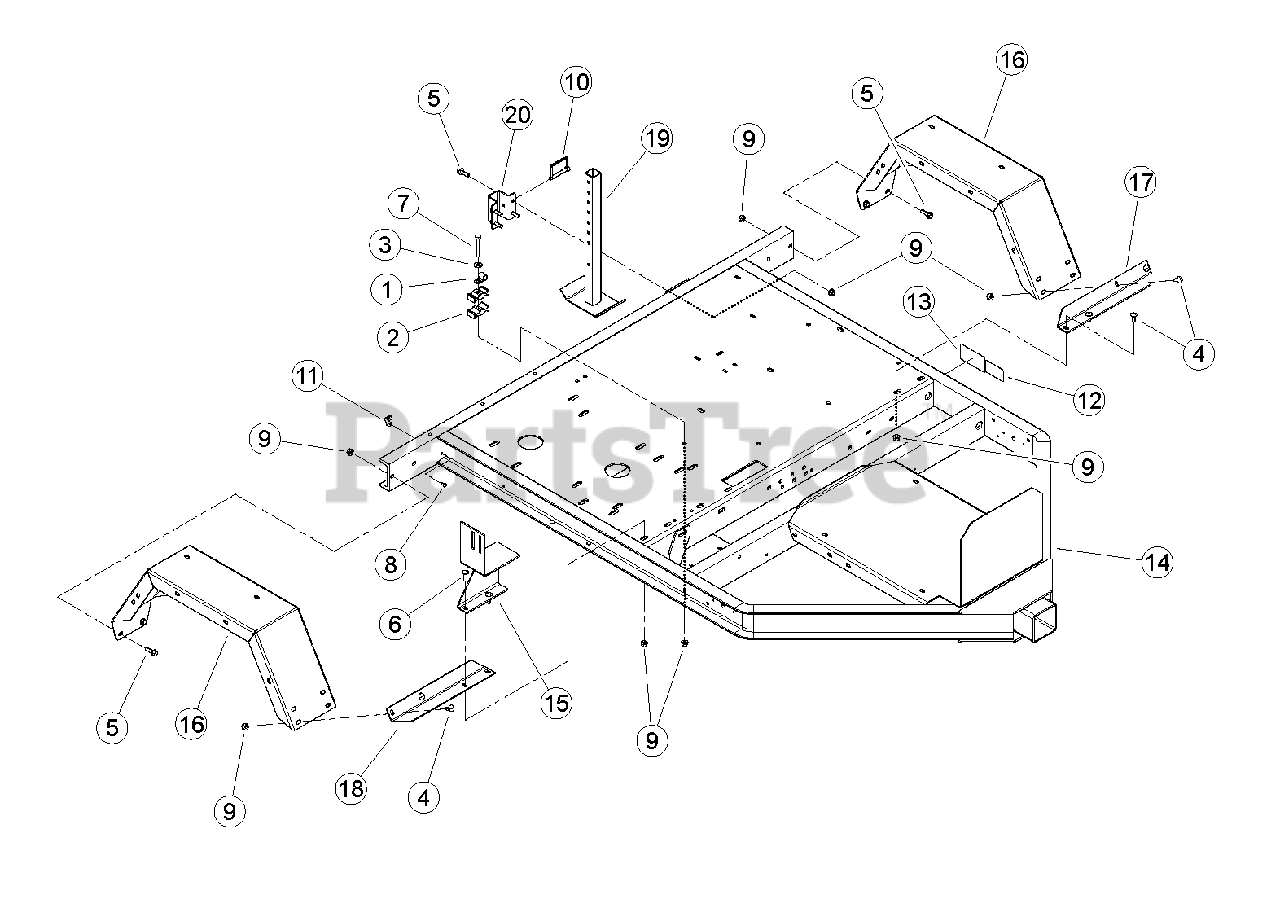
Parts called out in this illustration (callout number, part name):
1	CLAMP, 9/16 COATED
2	CLAMP, PLASTIC HOSE
3	WASHER, 3/8" FLAT ZP
4	BOLT, 3/8 X 1" GR5 CRG NC ZP
5	BOLT, 3/8 X 1-1/4 FLANGE NC
6	BOLT, 3/8 X 1-1/4" GR5 CRG NC ZP
7	BOLT, 3/8 X 2-3/4" GR5 NC HHCS ZP
8	RIVET, AL BLIND 1/4 X 3/4 DOME HEAD
9	NUT, 3/8-16 NYLOCK FLANGE
10	PIN, 3/8 X 2-3/4" SNAP
11	CLAMP, CABLE MOUNT
12	DECAL, P215/70R15 LOAD RATING
13	DECAL, EPA EMISSION
14	WELDMENT, CHIPPER TRAILER
15	WELDMENT, BELT GUIDE
16	FENDER, HEAVY DUTY
17	ANGLE, LH FENDER SUPPORT
18	ANGLE, RH FENDER SUPPORT
19	WELDMENT, REAR STABILIZER
20	GUIDE, TRAILER SUPPORT
